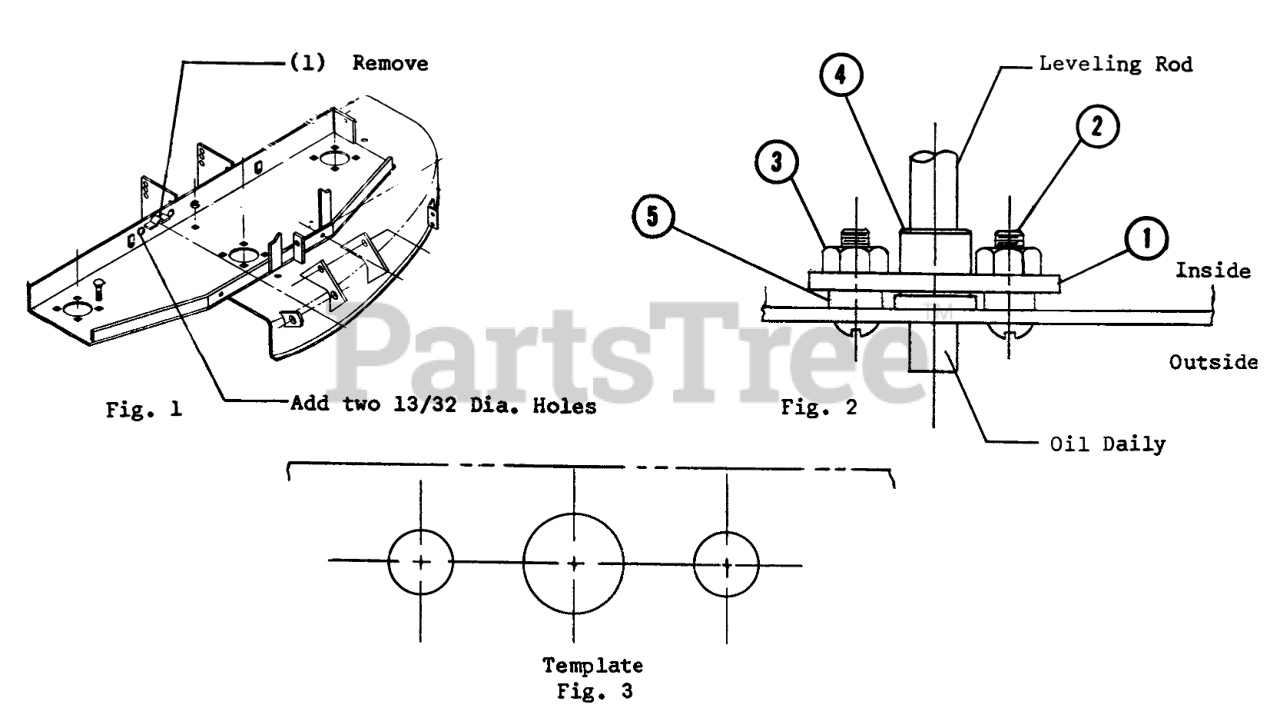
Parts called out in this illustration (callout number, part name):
1	Plate
2	Bolt 3/8-16 x 1 RD.HD.
4	BUSHING
5	Bushing
